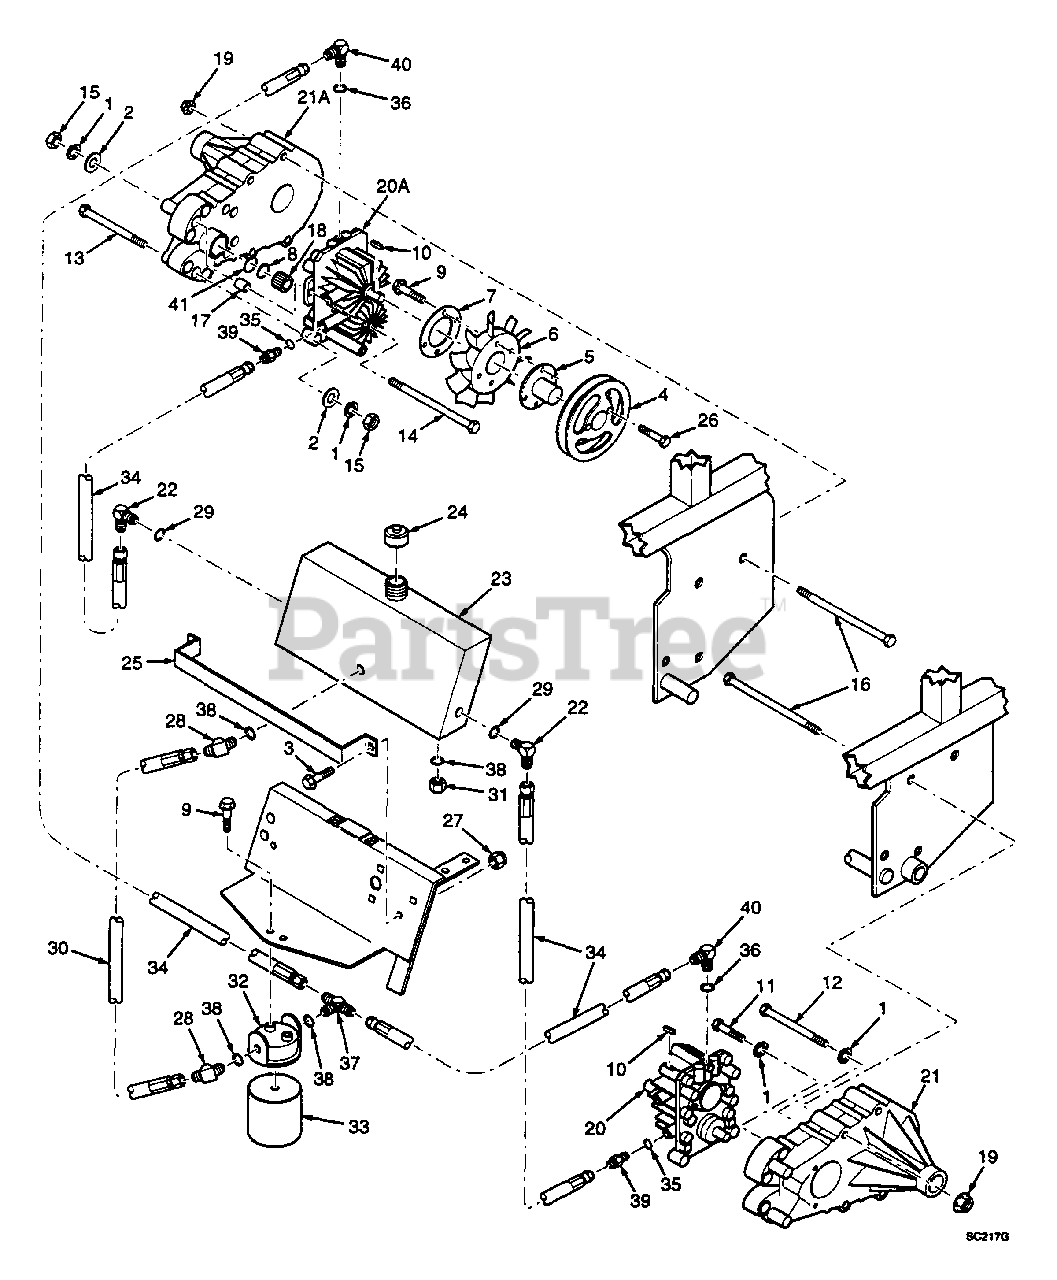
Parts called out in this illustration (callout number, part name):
1	Lockwasher, 5/16"
2	Flatwasher, 5/16" (.344 x .688 x .065)
3	Bolt, Serrated Flange Hex Head 1/4-20 x 3/4"
4	Pump, Pulley
5	Tapered Hub, 15mm Bore
6	Fan
7	Washer, Back-up
8	Snap Ring
9	Bolt, Serrated Flange Hex Head 1/4-20 x 1/2
10	Key, 5mm x 5mm x 25mm
11	Bolt, Hex Head 5/16-18 x 1-3/4"
12	Bolt, Hex Head 5/16-18 x 4-1/2"
13	Bolt, Hex Head 5/16-18 x 5"
14	Bolt, Hex Head 5/16-18 x 7-1/2"
15	Nut, Hex 5/16-18
16	Bolt, Hex Head 3/8-16 x 4"
17	Spacer
18	Gear
19	Nut, Serrated Flange Hex Head 3/8-16
20	Pump, LH
20A	Pump, RH
21	Axle, LH
21A	Axle, RH
22	Elbow,90 Degree 9/16-18 JIC to 9/16-18 "O" Ring
23	Oil Tank Reservoir
24	Cap, Oil Reservoir
25	Strap, Oil Reservoir
26	Bolt, Hex Head 1/4-20 x 1-1/4"
27	Nut, Elastic Stop 1/4-20
28	Elbow, 45 Degree 3/4-16 JIC to 3/4-16 "O" Ring
29	"O" Ring, 5/64 x 15/32 ID
30	Hose Assembly, Filter Inlet
31	Plug, 3/4-16 "O" Ring
32	Head, Oil Filter
33	Oil Filter, Special
34	Hose Assembly
35	"O" Ring, 3/32 x 3/4 ID
36	"O" Ring, 1/16 x 3/8 ID
37	1/2" T-fitting, 3/4-16 JIC to 3/4-16 "O" Ring
38	"O" Ring, 3/32 x 5/8 ID
39	Tube Union 3/4-16 JIC to 7/8-14 "O" Ring
40	Elbow, 90 Degree 9/16-18 JIC to 7/16-20 "O" Ring
41	"O" Ring
